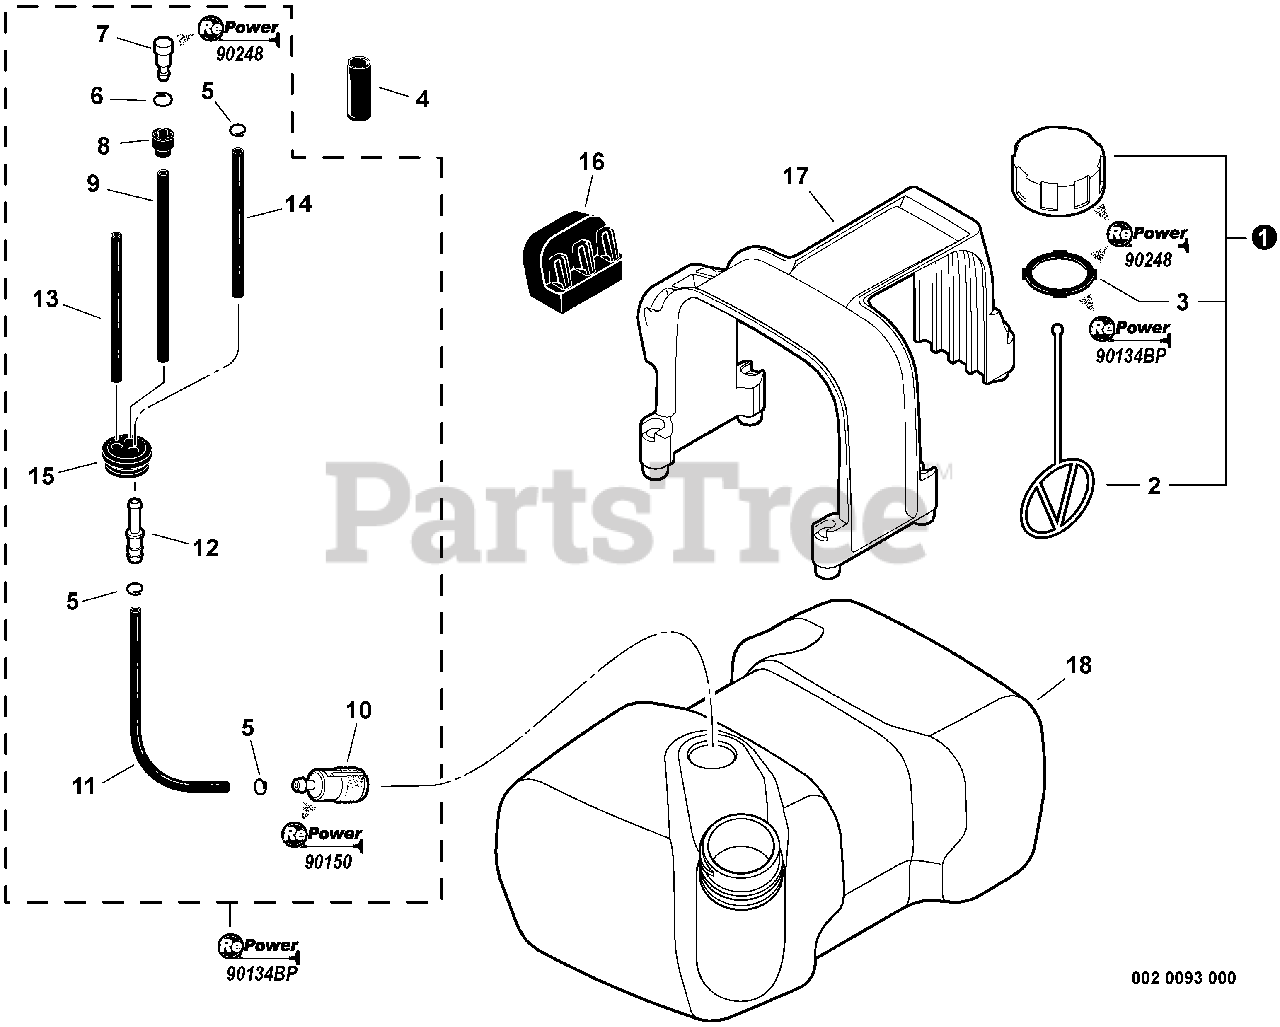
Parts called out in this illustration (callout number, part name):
1	CAP ASSY, FUEL
2	CONNECTOR, CAP L= 100 MM
3	GASKET, FUEL CAP
4	TUBE, FUEL LINE 16×18×L40
5	CLIP Ø6
6	CLIP Ø6.5 MM
7	VENT ASSY
8	HOLDER, VENT
9	PIPE, FUEL 3×6×130 BLACK
10	FILTER, FUEL
11	PIPE, FUEL 3×5×105L BLACK
12	CONNECTOR, PIPE Ø5ר3.5
13	PIPE, FUEL 2.4×5×200 BLACK
14	PIPE, FUEL 3×5×135L BLACK
15	GROMMET, FUEL
16	CUSHION
17	RETAINER, FUEL TANK
18	TANK, FUEL
19	FUEL SYSTEM KIT
20	TUNE-UP KIT - REPOWER
21	CAP/VENT KIT - REPOWER
